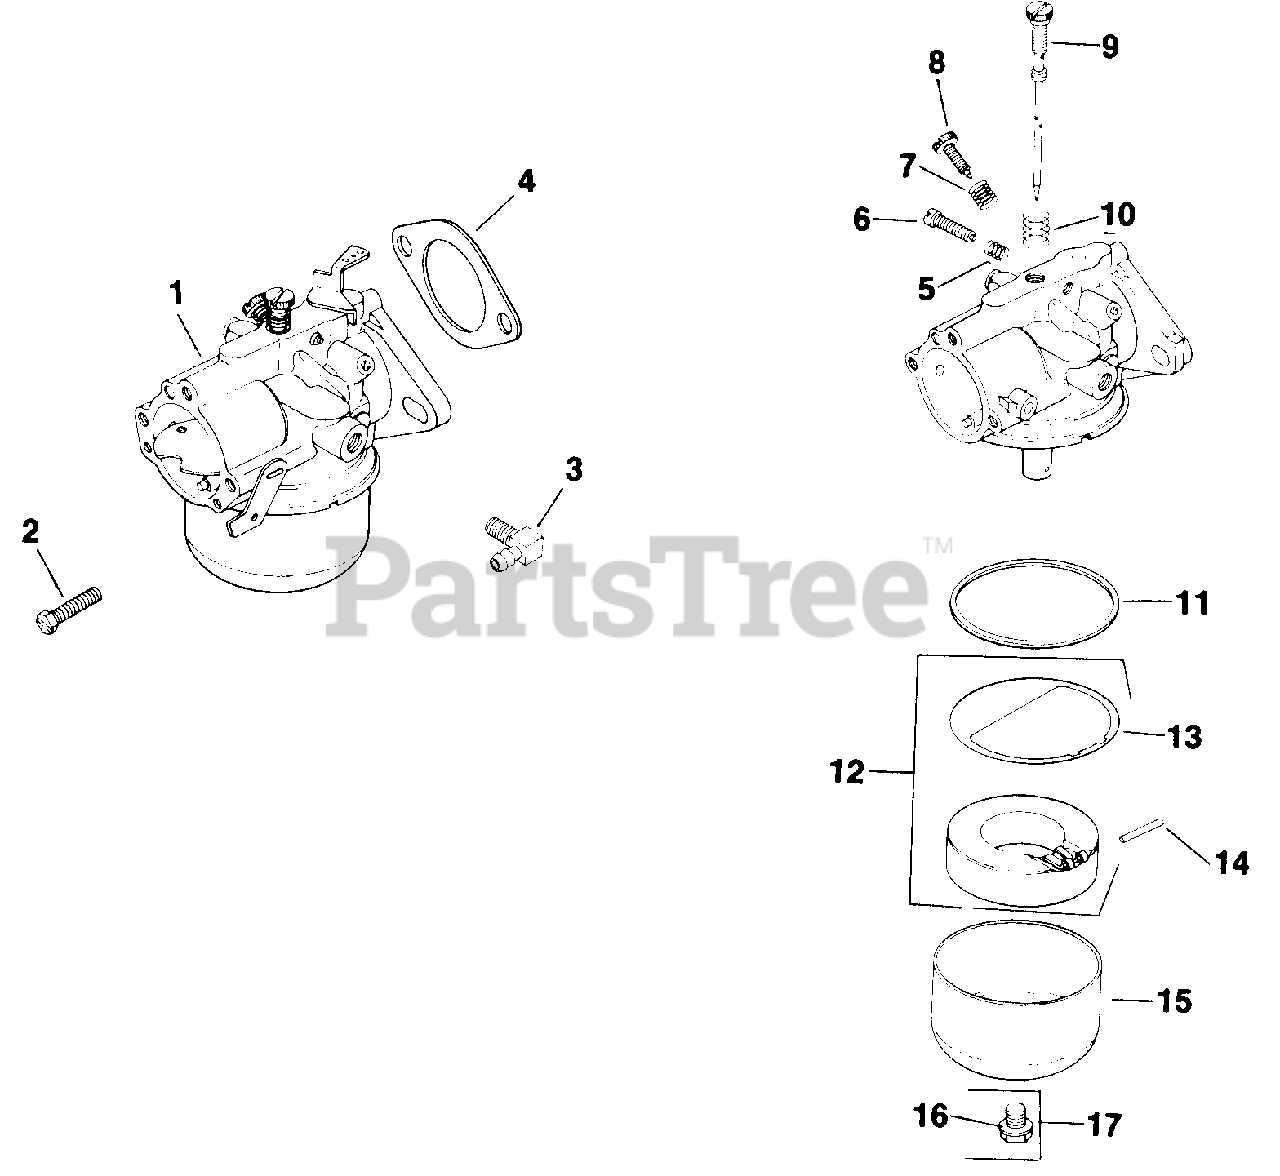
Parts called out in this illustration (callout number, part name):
1	Carburetor Assemlby (Includes 5-17)
2	Screw, Sltd. Hd. 1/4-20 x 3/4
3	Connector, 90ø Hose
4	Gasket, Carburetor
5	Spring, Idle Speed
6	Screw, Idle Speed Adj.
7	Spring, Idle Fuel
8	Needle, Idle Fuel Adj.
9	Needle, Main Fuel Adj.
10	Spring, Main Fuel
11	Gasket, Bowl
12	Kit, Float
13	Gasket, Bowl Baffle
14	Pin, Float Hinge
15	Bowl, Fuel
16	Gasket, Bowl Retainer Screw
17	Screw, Bowl Retainer
